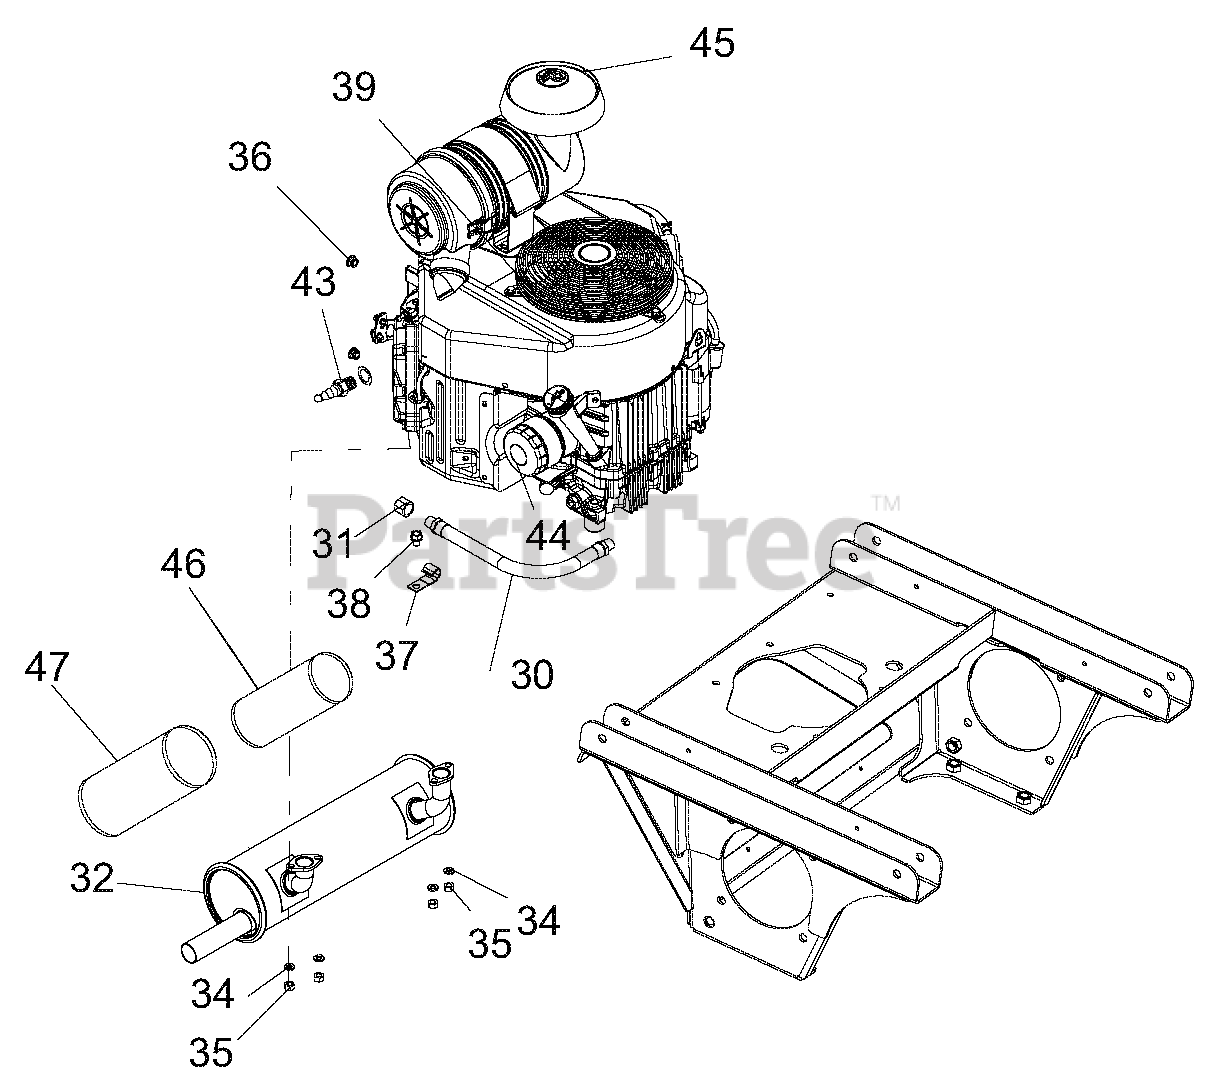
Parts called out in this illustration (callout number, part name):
30	HOSE, HYD .38-11-OK M6N0-M6N0
31	PIPE CAP 3/8 NPT FEMALE
32	MUFFLER, 27-31 FX KAW
34	WSHR-LK .31X.078 REG YWZC
35	NUT-LK-TOP M8-1.25 YWZC
36	NUT-LK-NYL-FLG .31-18 YWZC
38	SCR-TAP .38-16X.50 HWH TR YWZ
39	ENGINE, ENVIROGUARD, CONV. LP
43	SPARK PLUG (Set to .025 before installation)
44	OIL FILTER
45	CAP, AIR CLEANER INTAKE
46	FILTER, INNER
47	FILTER, OUTER
